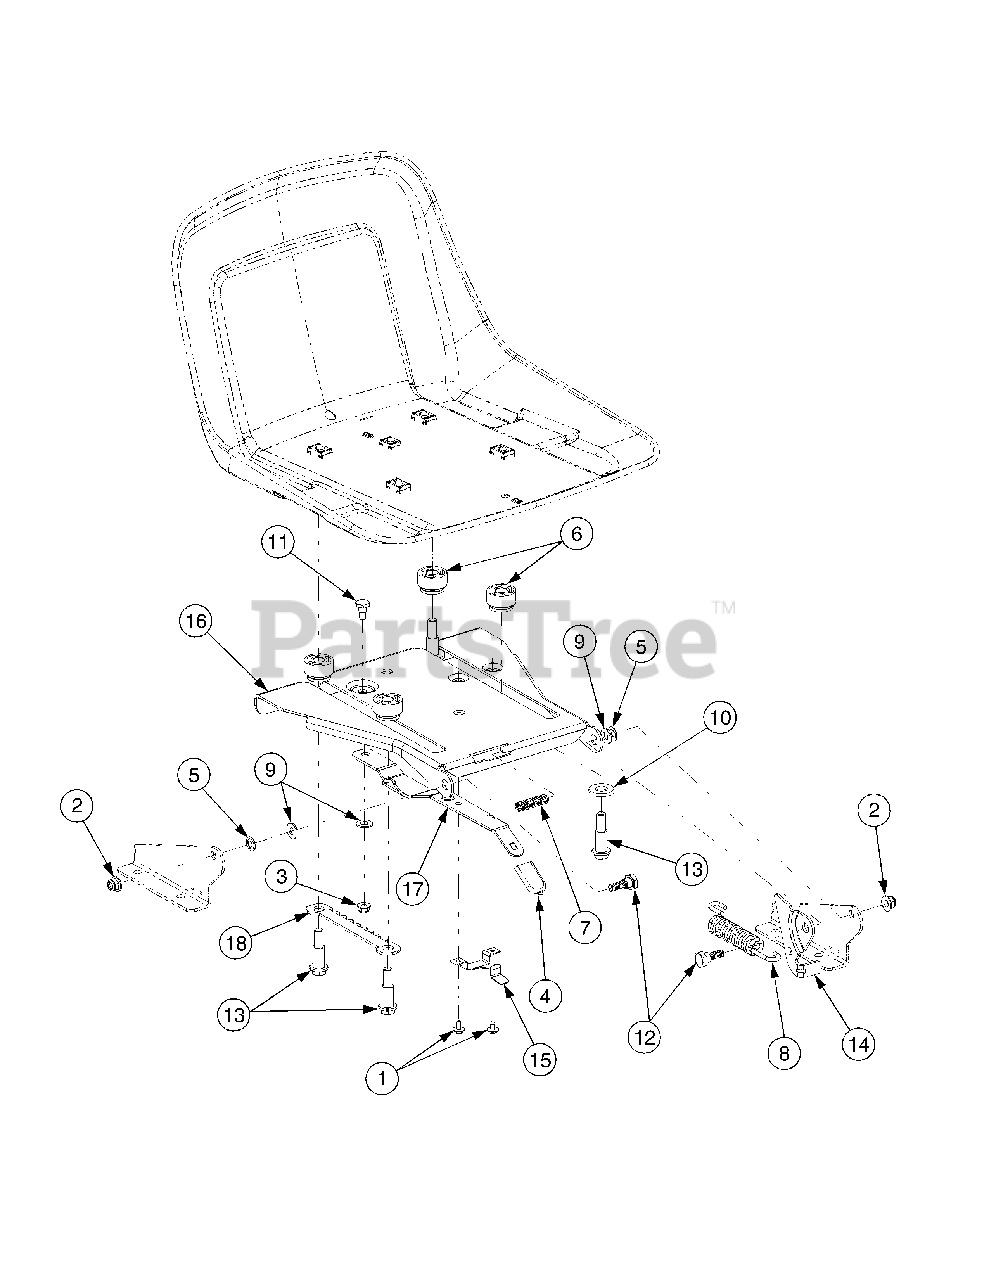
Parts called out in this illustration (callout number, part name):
1	Screw, Hx. Wash. Hd. Tapp #10-16 x .375
2	Nut, Hx Insert Flange Lck, 5/16-18 GrF
3	Nut, Hx Insert Flnge Lck, 1/4-20 GrF
4	Grip, Seat Adjustment
5	Nut, Speed, .3125
6	Spacer, Seat Adjustment
7	Spring, Compression, .41 x 1.5
8	Spring, Extension, .84 Dia. x 4.6
9	Washer, Flat, .344 x .688 x .065
10	Washer, Flat, .531 x 1.062 x .134 HT
11	Screw, Shoulder, .34 x .285:1/4-20
12	Screw, Shoulder, .437 x .268:5/16-18
13	Screw, Shoulder, .5 x .925:3/8-16 ...
14	Bracket, Seat Lift
15	Stop, Seat Adjustment
18	Index Bracket, Seat Adjustment
